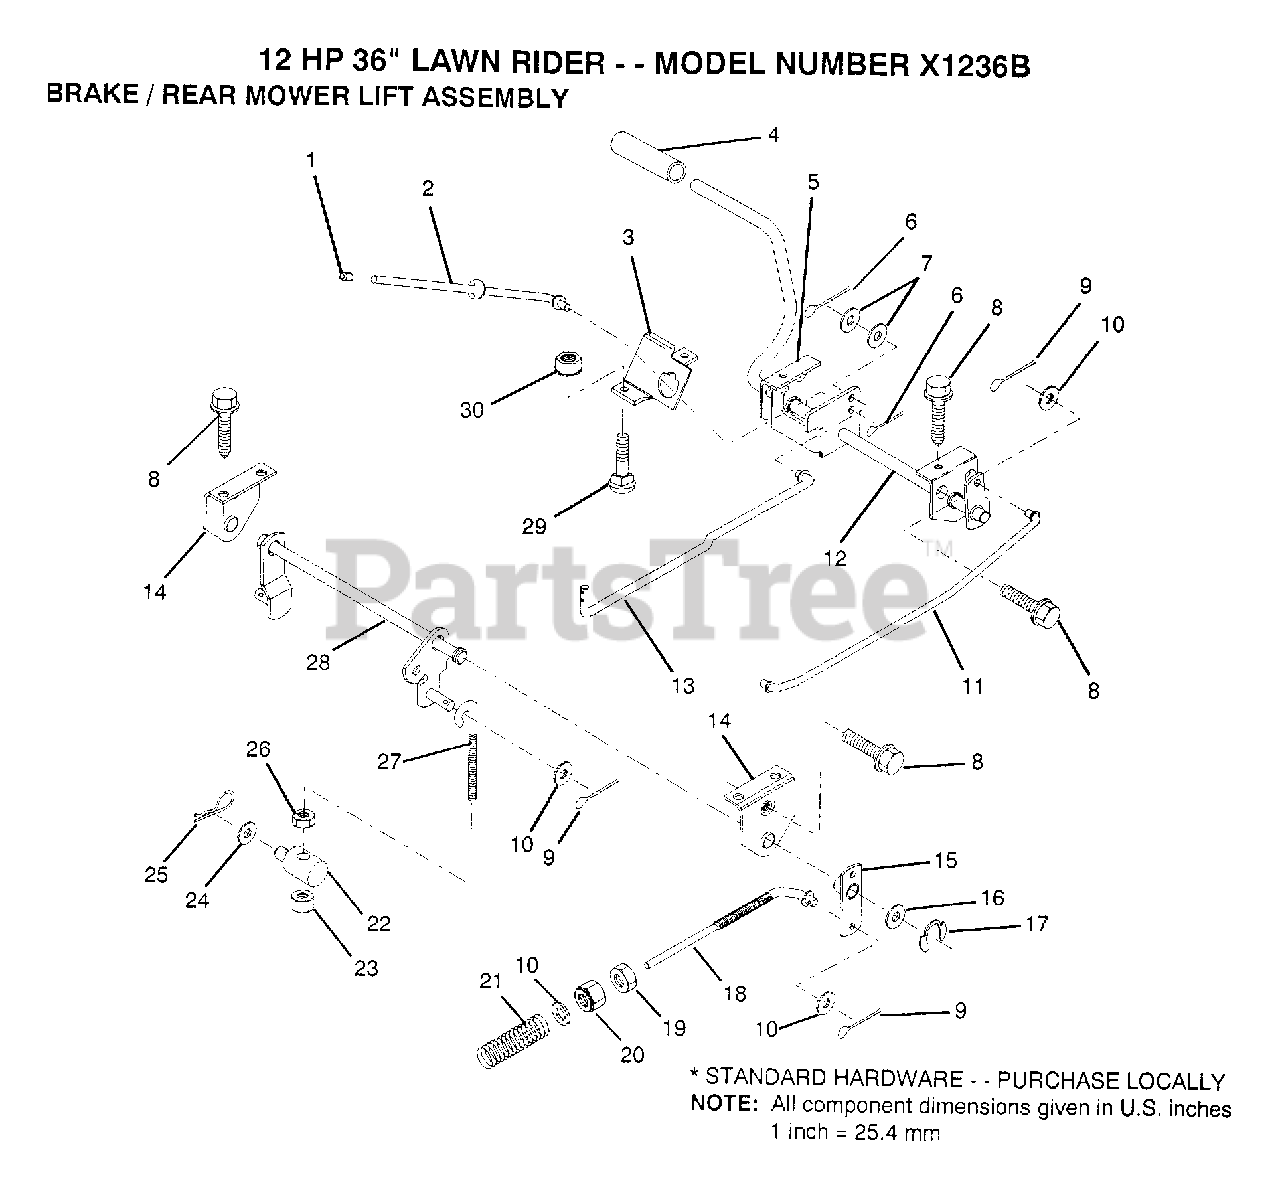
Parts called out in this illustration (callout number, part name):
1	PLUNGER CAP T
2	"ROD,PARK BRAKE"
3	"BRKT,PARK BRAKE"
4	PEDAL COVER T
5	"BRKT,CLU PEDAL LH"
7	WASHER
8	SCREW LT
9	COTTER PIN
10	WASHER
11	"ROD,FRT BRAKE"
13	"ROD,CLUTCH"
14	"BRKT,LIFT SHAFT"
15	BRAKE PIVOT ARM
16	WASHER T
17	KLIP RING
19	NUT
20	NUT
21	SPRING ROD LT
24	WASHER
25	SPRING.RETAINER
26	LOCKNUT
27	"LINK, MOWER REAR"
